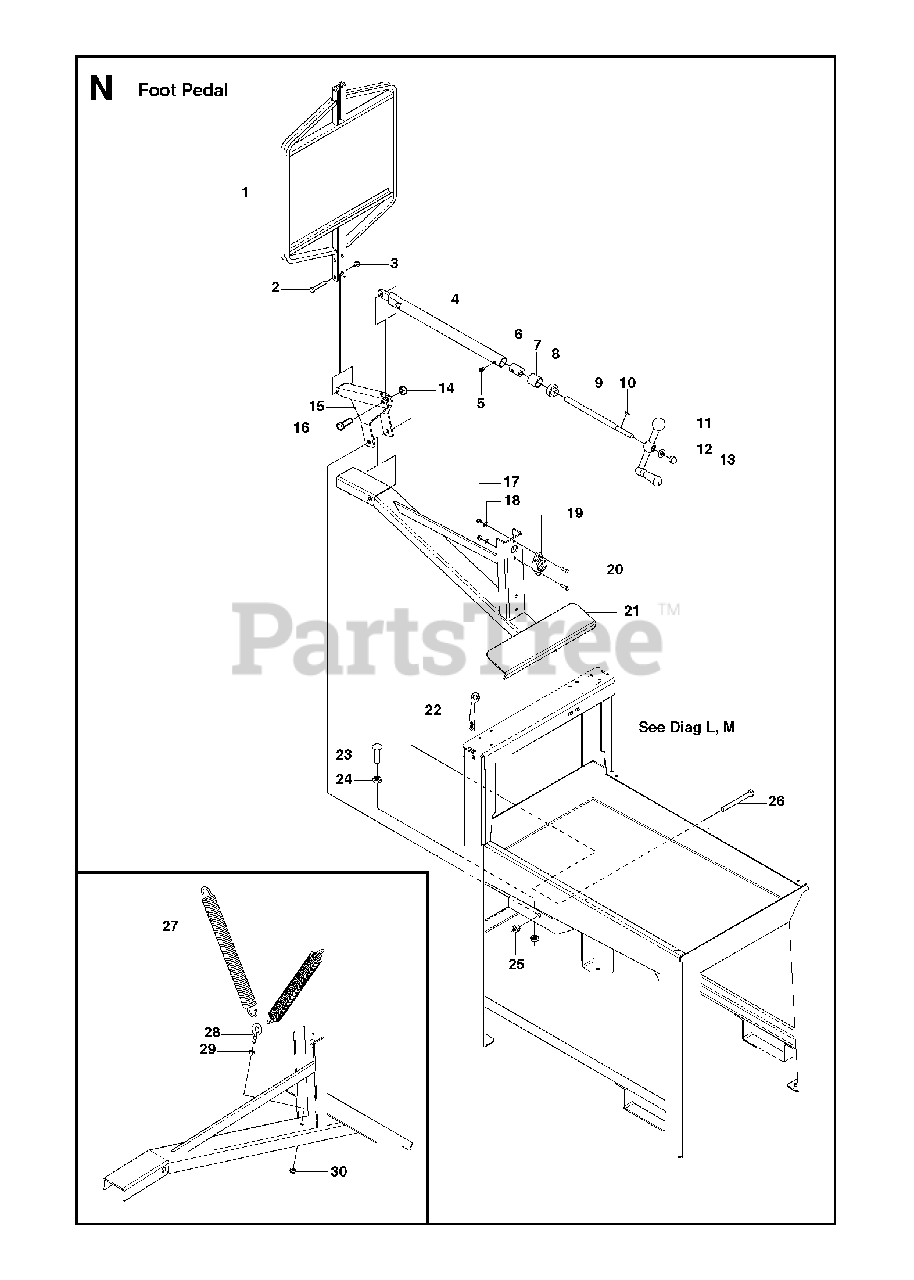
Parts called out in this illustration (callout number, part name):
3	NUT
14	NUT
18	FS900T RINGS/WASHER,1/4 PLAIN
25	NUT
30	NUT
